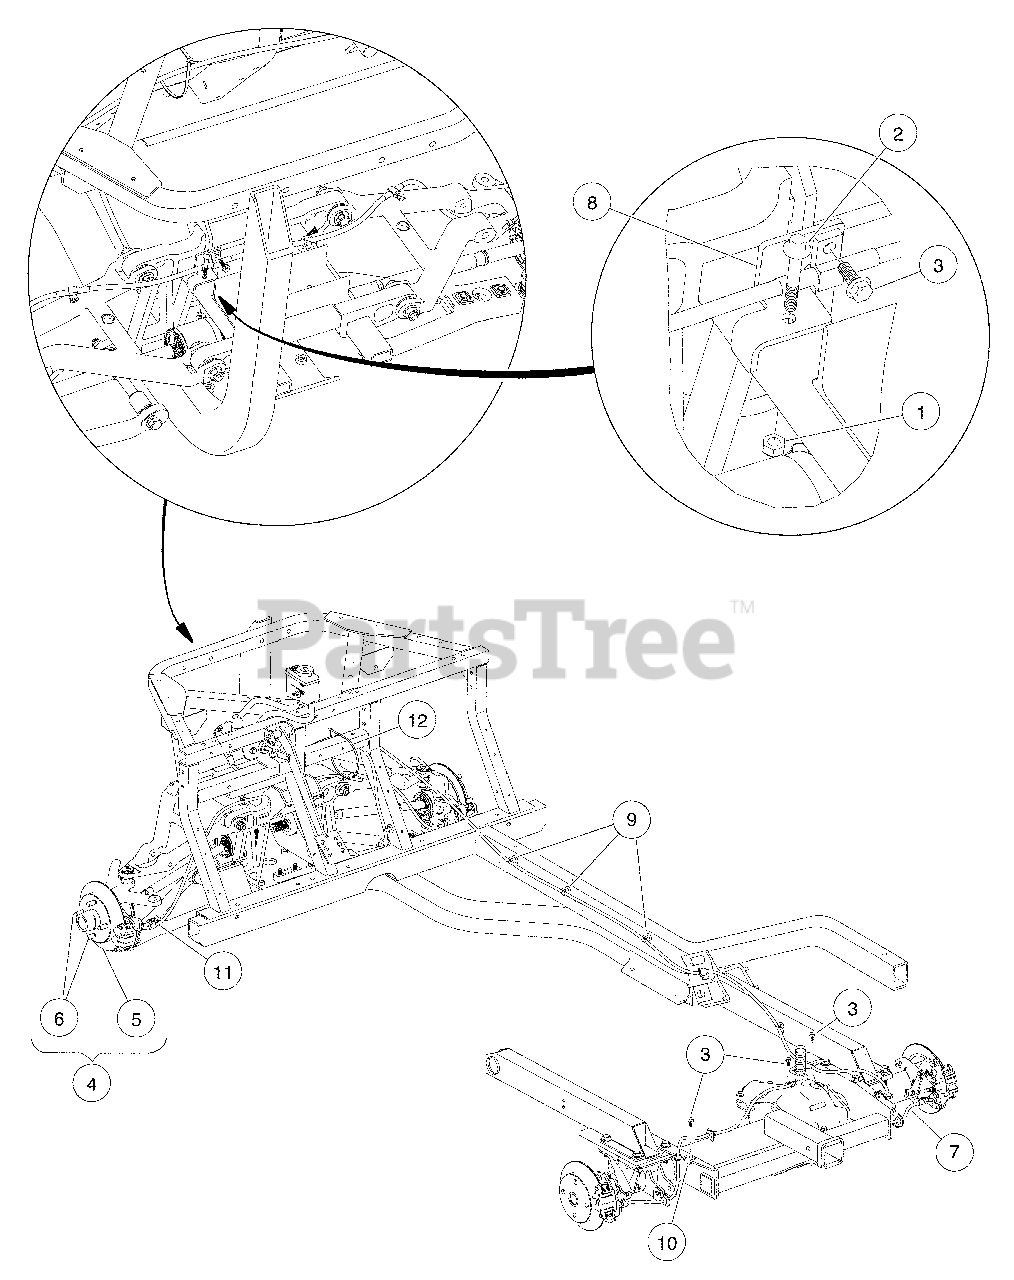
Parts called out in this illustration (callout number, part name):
1	Locknut, M6-1.00 Nylon Insert
2	Bolt, Flanged Head, M6x1.0x40
3	Screw, M6 X 16 Tt Hx Fl Hd
4	Assy, Rotor, Brake, Front, Wt
5	Rotor, Brake, Front, Wt.
6	Stud, Wheel Lug
7	Assembly, Brake Line, Rear
8	Bracket, Tee, Brakeline
9	Clip, Brake Line.
10	Bracket, Line, Hydraulic.
11	Brakeline, Front, Assembly
12	Tie Wrap, 11" Nylon
